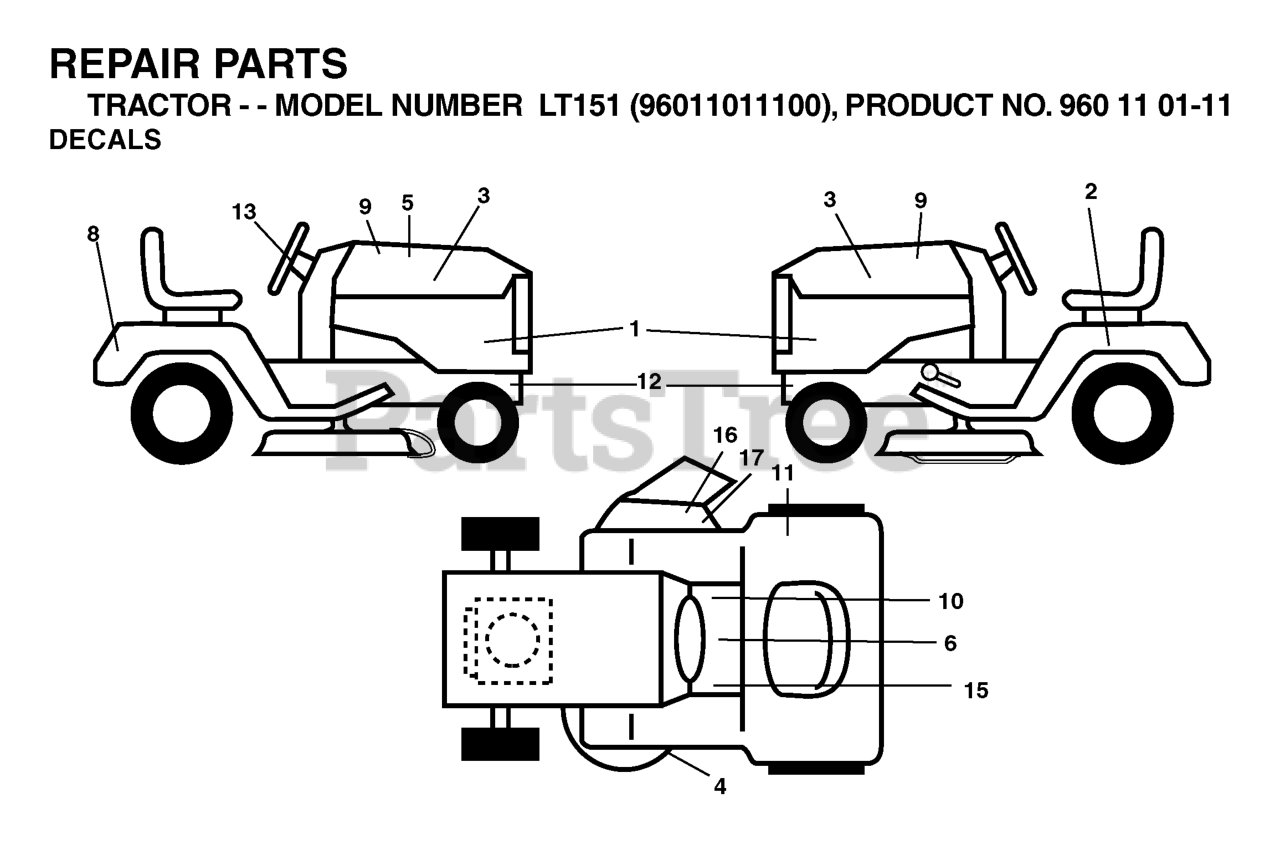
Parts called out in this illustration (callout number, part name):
2	DECAL BTRY SYMBOLS
3	DECAL.HOOD.HUSQVARNA.INTERNATI
4	DECAL.V-BELT.SCHEMATIC.36/38/9
6	LABEL
9	DECAL.HOOD.HUSQVARNA.INTERNATI
10	DECAL PARK BRAKE
11	Decal, Fender 100 DB/CE
13	DECAL.STEERING.HUSQ.BLUE
15	DECAL
16	DECAL.INTERNATIONL.CUTFINGER
17	DECAL, DEFLECT WARNING
